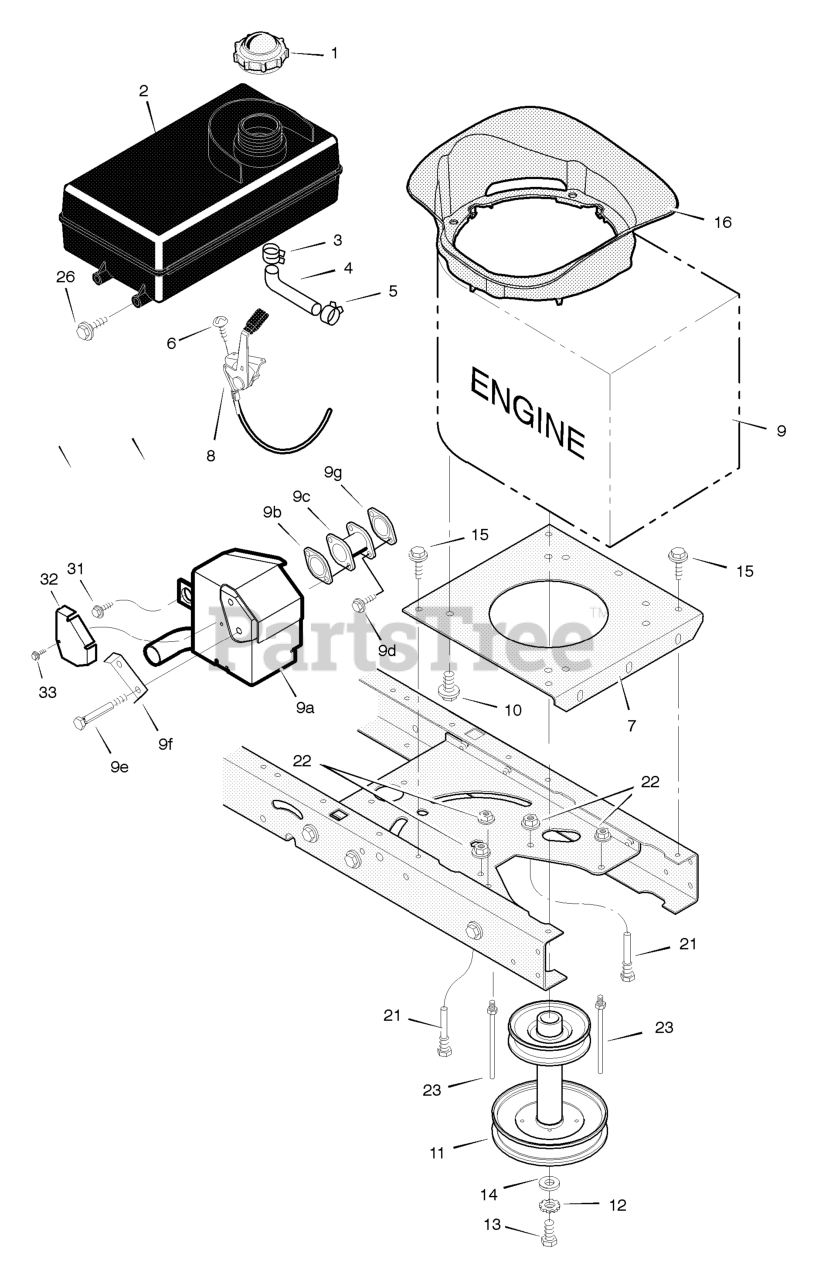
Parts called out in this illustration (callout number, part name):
1	Fuel Cap
2	TANK, Fuel 1.4 Gal.
3	Hose Clamp
4	Fuel Line (Must cut to length)
5	Hose Clamp
7	Plate, Engine
8	Throttle Control
9	Engine *
9A	Muffler and Heat Shield
9B	GASKET, Exhaust
9C	Adapter, Muffler
9D	Screw, Adapter
9E	Bolt, Muffler
9F	Lock, Screw
9G	Gasket, Muffler
10	Bolt, Engine Mount
11	STACK PULLEY ASSEMBLY
12	Lockwasher
13	Bolt, Hex
21	Guide, Belt
22	Nut, Flange
23	Guide, Belt
26	Screw *
31	Screw *
32	Cover, Heat Shield
33	Screw *
